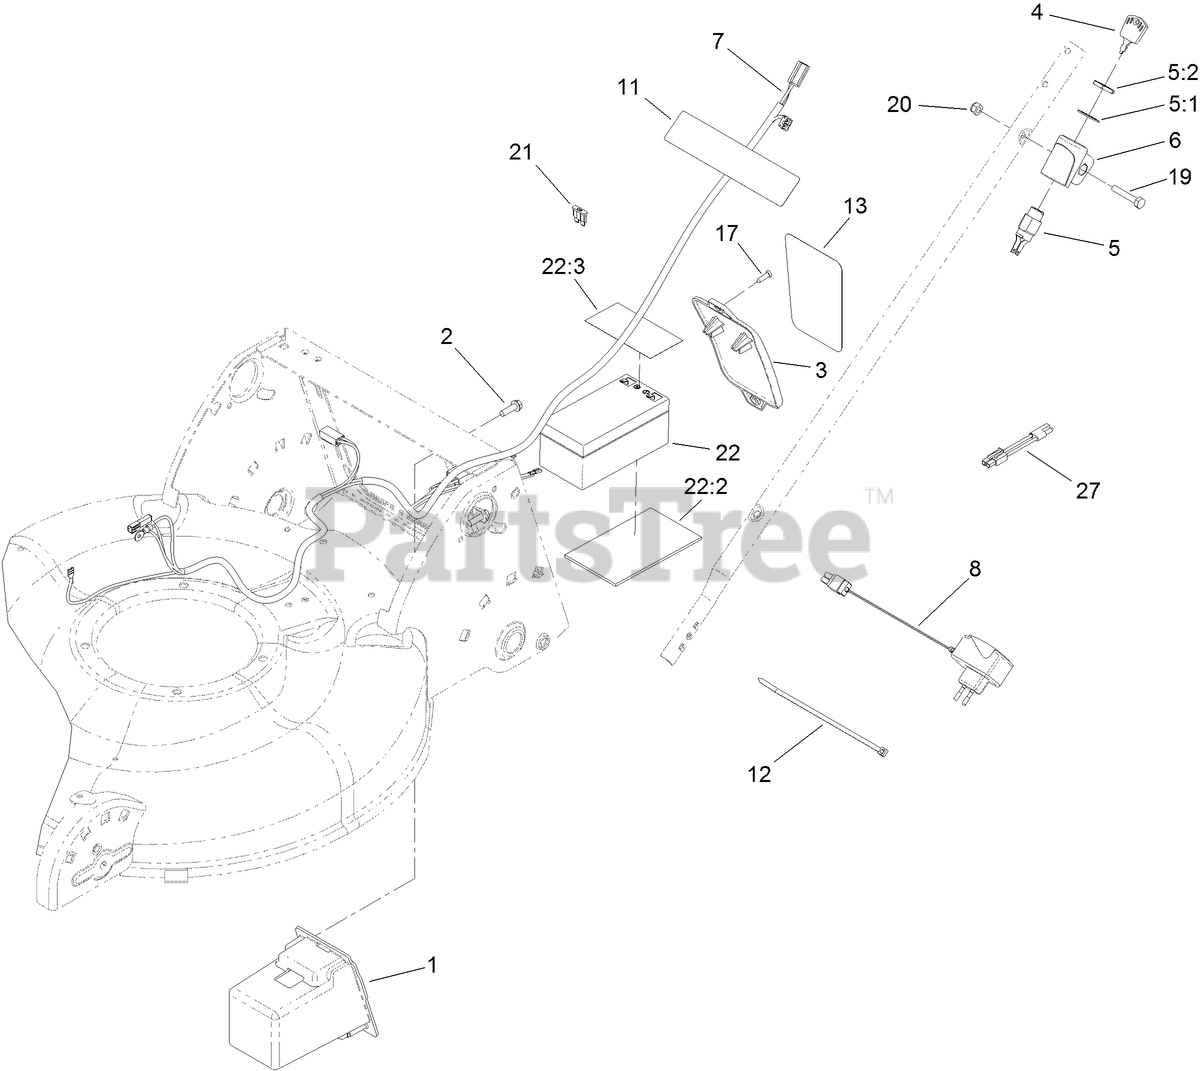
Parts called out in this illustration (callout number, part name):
1	BOX-BATTERY
2	SCREW-HWH
3	COVER-BATTERY
5	STARTER SWITCH ASM
5:1	WASHER-LOCK
6	MOUNT-SWITCH
7	HARNESS-WIRE
8	CHARGER-EUROPEAN, 12V DC
11	DECAL-WARNING
12	TIE-CABLE
13	DECAL-INSTRUCTION, BATTERY
17	SCREW-PPH
19	SCREW-HH
20	NUT-LOCK, NI
21	FUSE-40 AMP
22	BATTERY-WET
22:2	FOAM-BATTERY
22:3	DECAL-TERMINAL, BATTERY
27	ADAPTER-CHARGER
